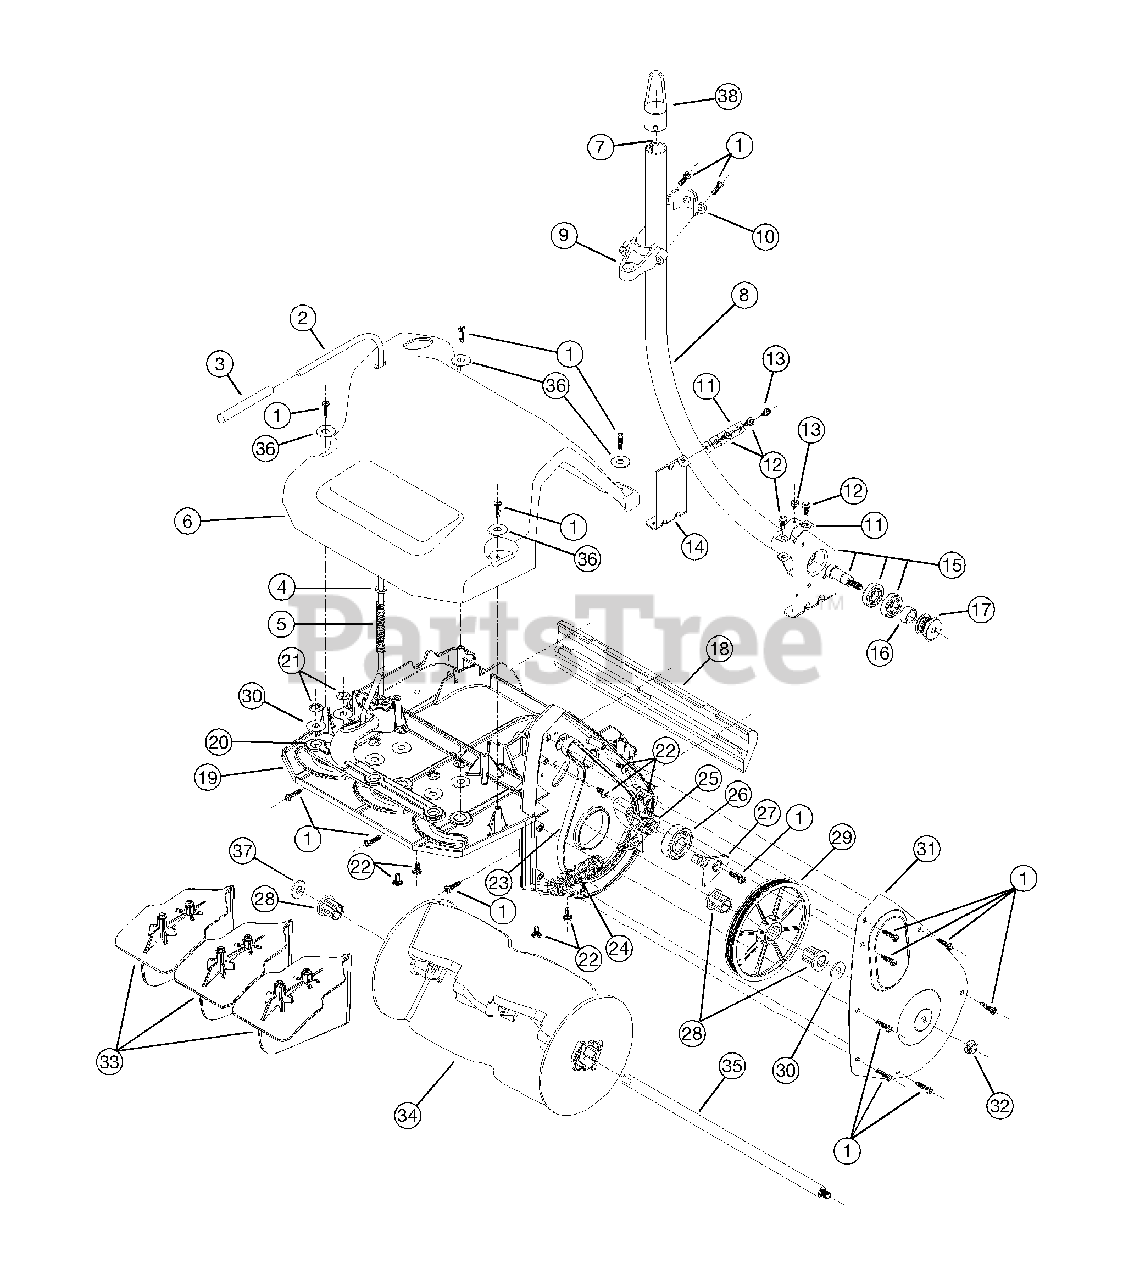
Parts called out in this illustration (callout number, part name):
2	Vane Control Handle
4	Washer
5	Spring
6	Cover
7	Flex Shaft
8	Drive Shaft Assembly
9	Clamp, LH
10	Clamp, RH
13	Screw, Anti-rotation
14	Drive Housing Bracket, RH
15	Drive Housing Bracket, LH
16	Spacer
17	Drive Pulley
18	Scraper
19	Snow Thrower Housing
20	Vane Control
21	Pushnut
23	Drive Belt
24	Spring
25	Idler Arm
26	Ball Bearing
27	Keeper
28	Flange Bearing
29	Driven Pulley
30	Washer
31	Belt Case Cover
32	Flange Lock Nut
35	Rotor Shaft
38	Hanger Accessory
